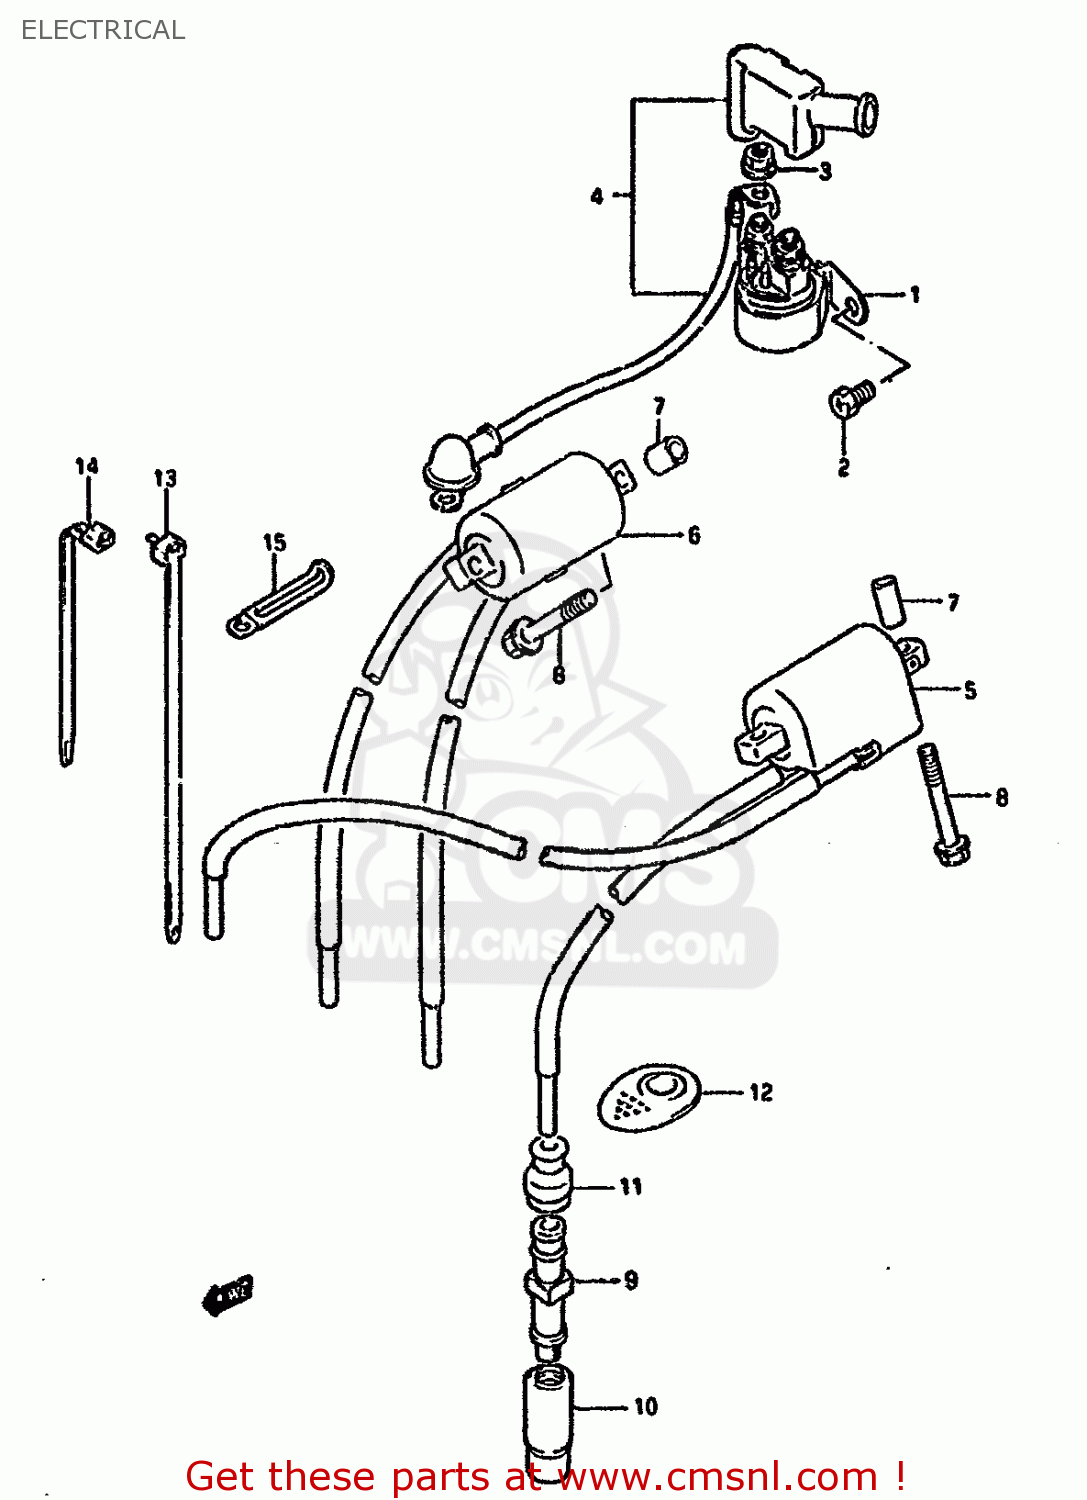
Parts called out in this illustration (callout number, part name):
1	RELAY ASSY,STARTING MOTOR
2	SCREW(6X8)
3	NUT
4	WIRE,STARTER MOTOR LEAD
5	COIL ASSY,IGNITION
6	COIL ASSEMBLY,IGNITION (2
7	SPACER(6.2X12X16)
8	SCREW
9	CAP,SPARK PLUG
10	SEAL,SPARK PLUG
11	SEAL,HIGH TENSION CORD
12	COVER,SPARK PLUG CAP
13	CLAMP
14	CLAMP(L:125)
15	CLAMP
